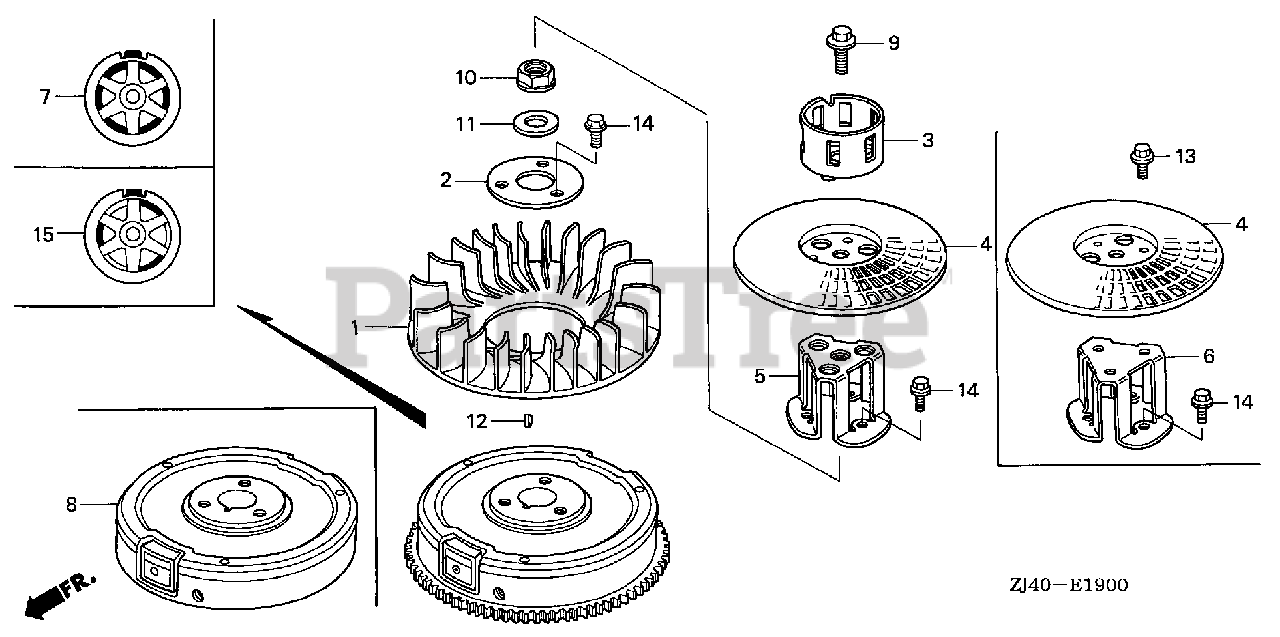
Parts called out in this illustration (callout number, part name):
1	FAN, COOLING
3	PULLEY, STARTER
4	GRID, SCREEN
5	SPACER, STARTER PULLEY MOUNTING
9	BOLT, UBS (12X28)
10	NUT, FLANGE (20MM)
11	WASHER (20MM)
12	KEY, SPECIAL WOODRUFF (25X18)
14	BOLT, FLANGE (8X16)
